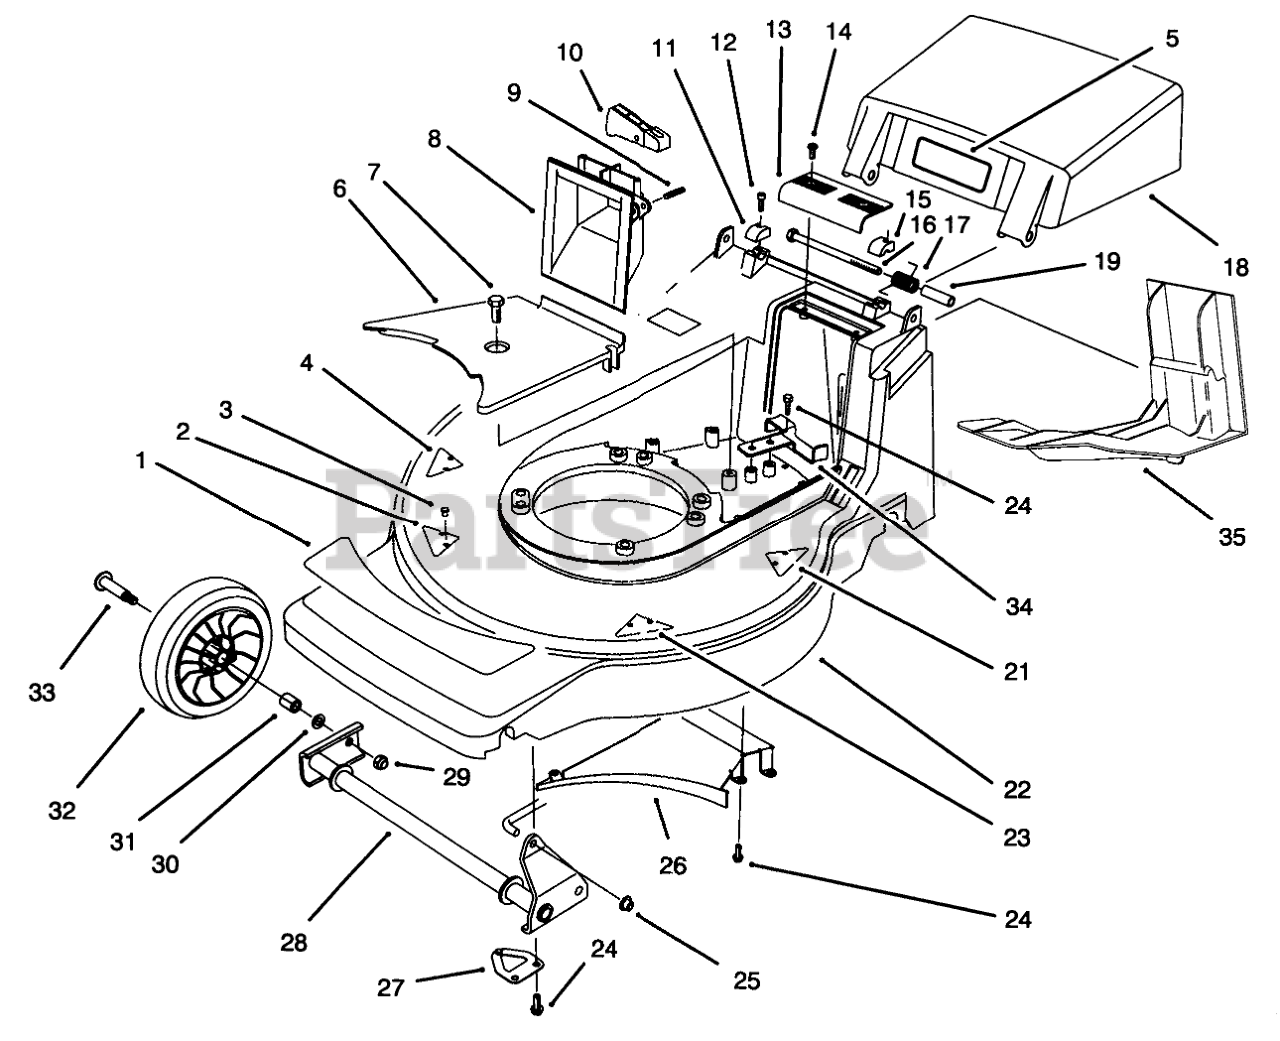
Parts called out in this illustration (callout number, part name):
1	DECAL - DECK
2	KICKER
3	SCREW-PPH
4	KICKER
5	DECAL-DANGER
6	BELT COVER
7	SCREW-HWHTF
8	GRIP - LOWER
9	PIN-SPIRAL
10	TRIGGER - HOC
11	CAP-HINGE BOLT, RH
12	SCREW-HSH
13	GRIP-UPPER
14	SCREW-PPH, PLASTITE
15	CAP-HINGE BOLT, LH
16	SCREW-HH
17	SPRING-DOOR
18	Door Discharge
19	SPACER-DOOR
21	KICKER
22	Housing-Deck (Incl. Ref. #2-4, 20, 21, & 23)
23	KICKER
24	SCREW-HWH
25	NUT-PUSH
26	Ramp-Discharge
27	SHAFT RETAINER ASM
28	FRONT PIVOT WA
29	NUT-HEX
30	WASHER
31	BUSHING
32	Wheel & Tire Assembly 7" (Incl. Ref. #31)
33	BOLT-WHEEL
34	REAR BELT GUIDE
35	DISCHARGE PLUG
